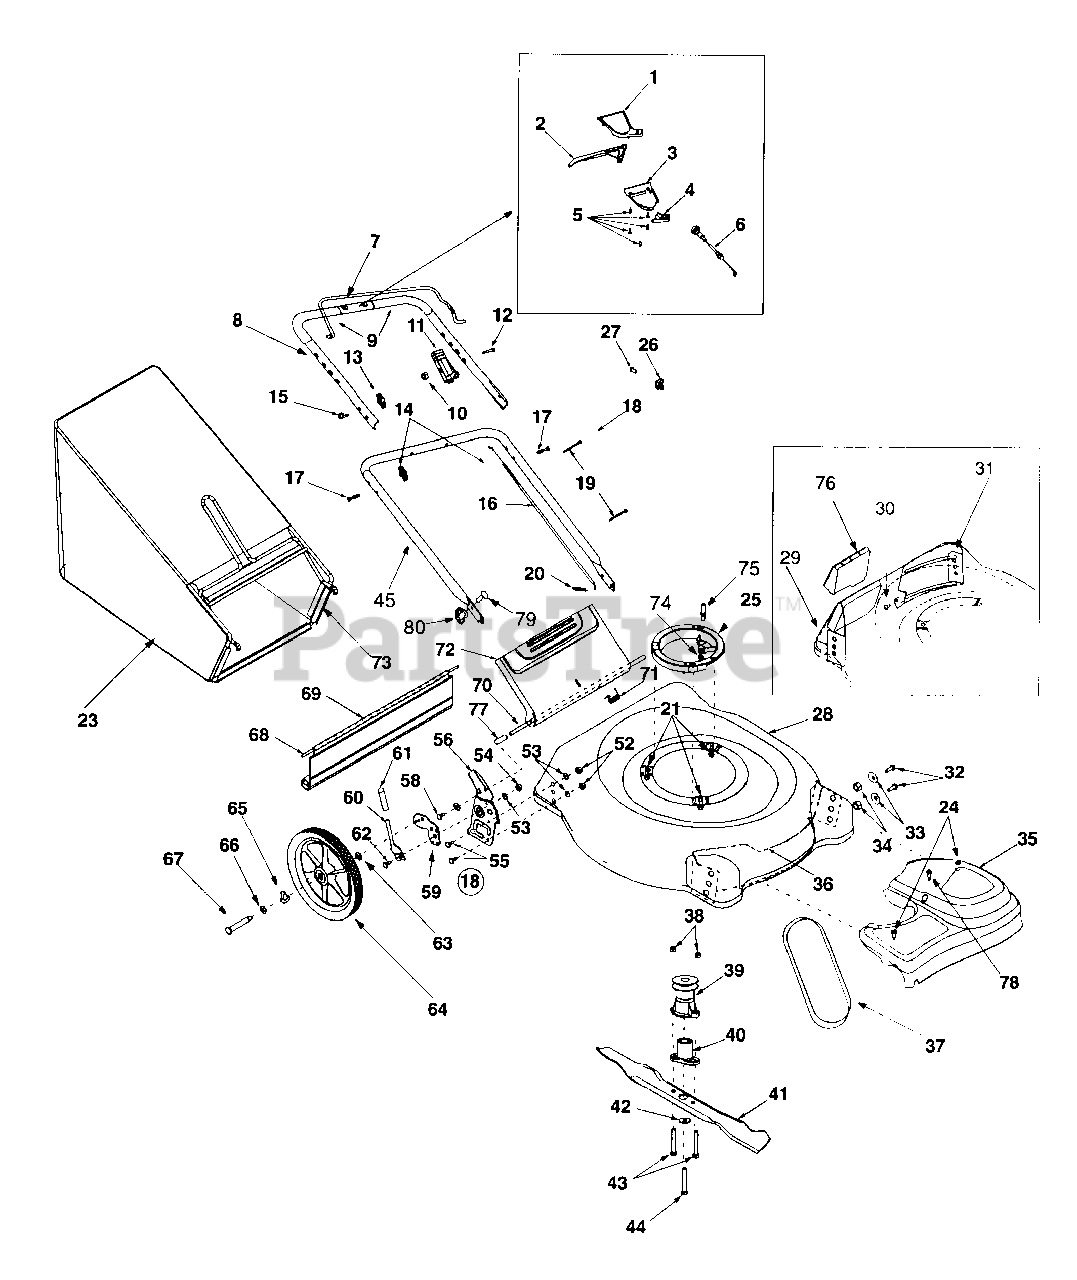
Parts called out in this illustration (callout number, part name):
1	Upper Drive Cover
2	Drive Lever
3	Lower Drive Cover
4	Mounting Cap
5	Screw # 10-16 x .625
6	Drive Cable
9	Foam Grip, 9"
10	Hex Lock Nut, 1/4-20
11	Throttle Housing
12	Oval C-Sunk Screw 1/4-20 x 1.31
13	Handle Knob
14	Handle Knob
15	Eye Bolt
16	Control Cable, 39"
17	Carriage Bolt 5/16-18 x 2.0
18	RH Bracket Ass'y
19	Cable Tie
20	Cotter Pin
21	Self-tapping Screw
23	Grassbag w/logo
24	Shoulder Screw # 12 -24
25	Engine Spacer
26	Clamp Casing
27	Hex Screw TT #10-32 x .625
30	Screw AB: 1/4-14: .625
32	Hex Screw 3/8-16 x .75
33	Bell Washer .39 x 1.13 x .062
34	Hex Nut 3/8-16
35	Transmission Cover
38	Hex Nut 1/4-20
39	Drive Pulley
40	Blade Adapter
41	21" Mulching Blade
42	Flat Washer .516 x 1.5 x .134
43	Hex Screw 1/4-20 x 1.50
44	Hex Screw 3/8-24 x 2.50
52	Hex Nut 3/8-16
53	Bell Washer .39 I.D. x 1.38 O.D.
54	Hex Flange Lock Nut 3/8-16
55	Hex Scr. w/Washer 1/4-14 x .625
58	Hex Screw TT 1/4-20 x .500
59	RH Pivot Bar
60	Height Adj. Lever
61	Foam Grip
62	Shoulder Scr .500 Dia. x .434
63	Washer .401 x .870 x .063
64	Wheel, 14 x 2 Yellow
65	Spring Washer .50 I.D. x 1.0 O.D.
66	Flat Washer .510 x 1.373 x .04
67	Shoulder Screw
68	Wire
69	Rear Trailing Shield
70	Pivot Rod
71	Torsion Spring
74	Hex Nut
75	Screw
76	Plastic Mulching Baffle
77	Spacer .375 x .50 x 1.02" Lg.
78	Shoulder Screw 1/4-14
79	Carriage Bolt 1/4-20
80	Wing Nut
